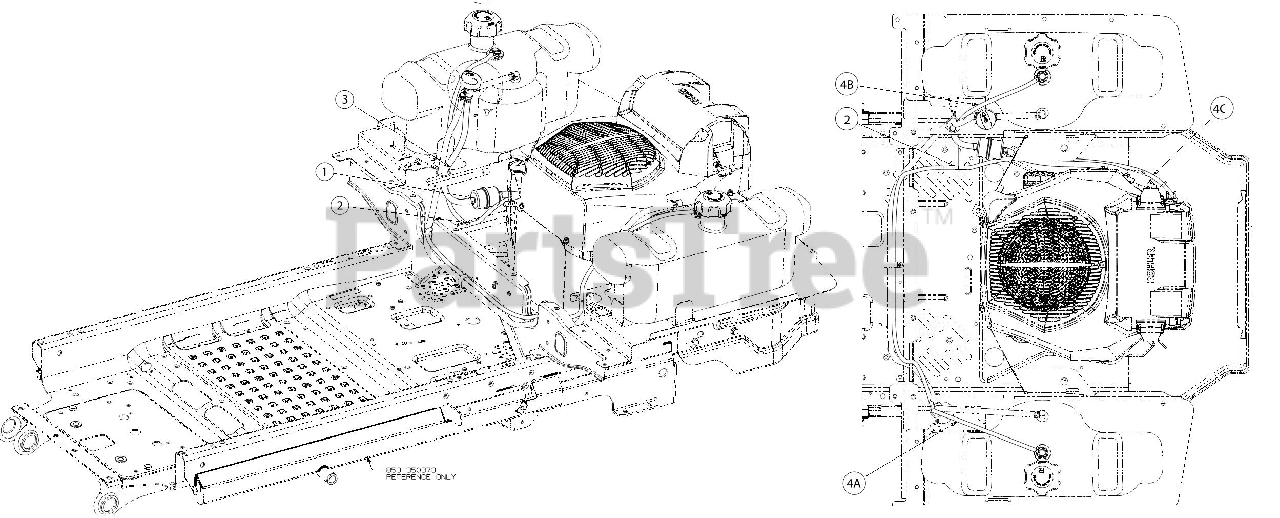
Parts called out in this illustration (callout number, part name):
1	HOSE CLAMP 1/20
2	FUEL FITTING
3	FUEL HOSE LOW PERMEATION
4A	VENT HOSE 3/16 ID
4B	VENT HOSE 3/16 ID
4C	VENT HOSE 3/16 ID
